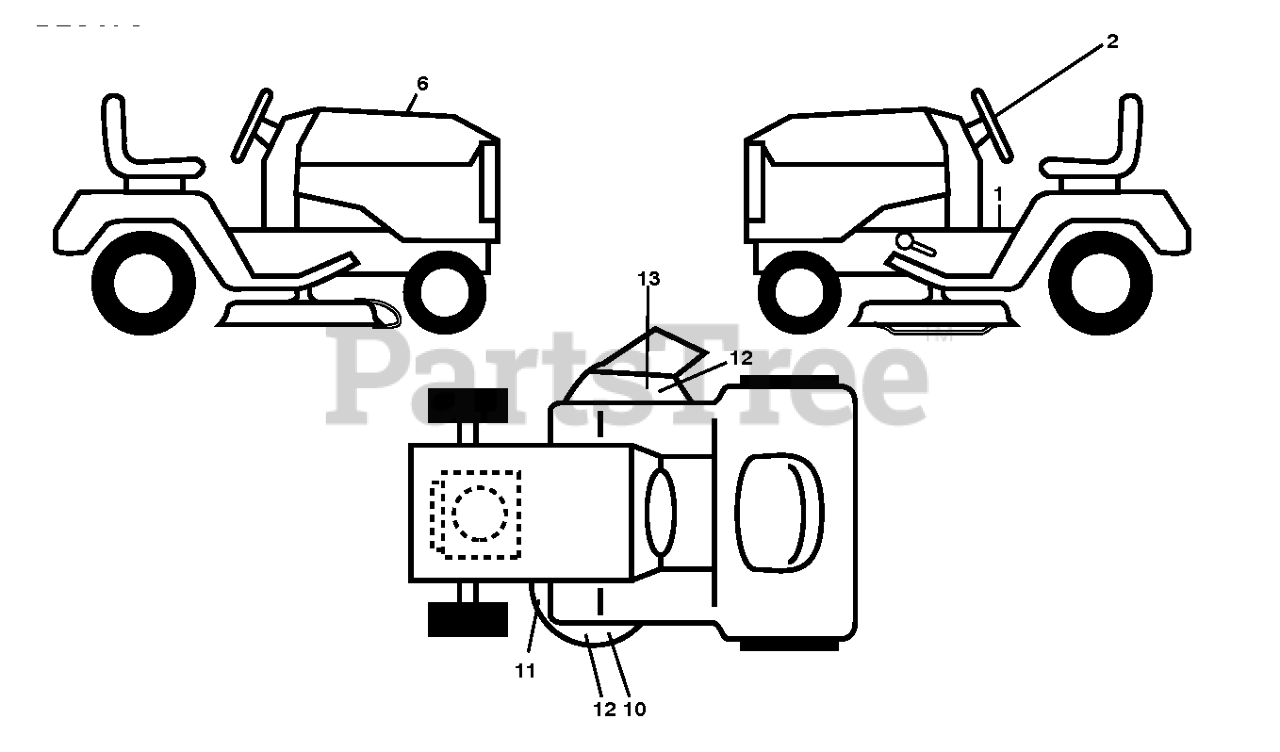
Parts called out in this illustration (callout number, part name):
1	DECAL.FENDER.WARNING.ENGLISH
2	DECAL STEERING WHEEL DECAL DEC
6	DECAL.RPL.KAW.FR.TLB.48F.K46L
10	DECAL CLIP.TRIM.W DECAL.DECK.L
11	DECAL.MOWER.SCH.48/54.PREM
12	DECAL.DECK.CLEARCUT.NOSTEP
13	DECAL DECK WARNING GRAPHIC DEC
